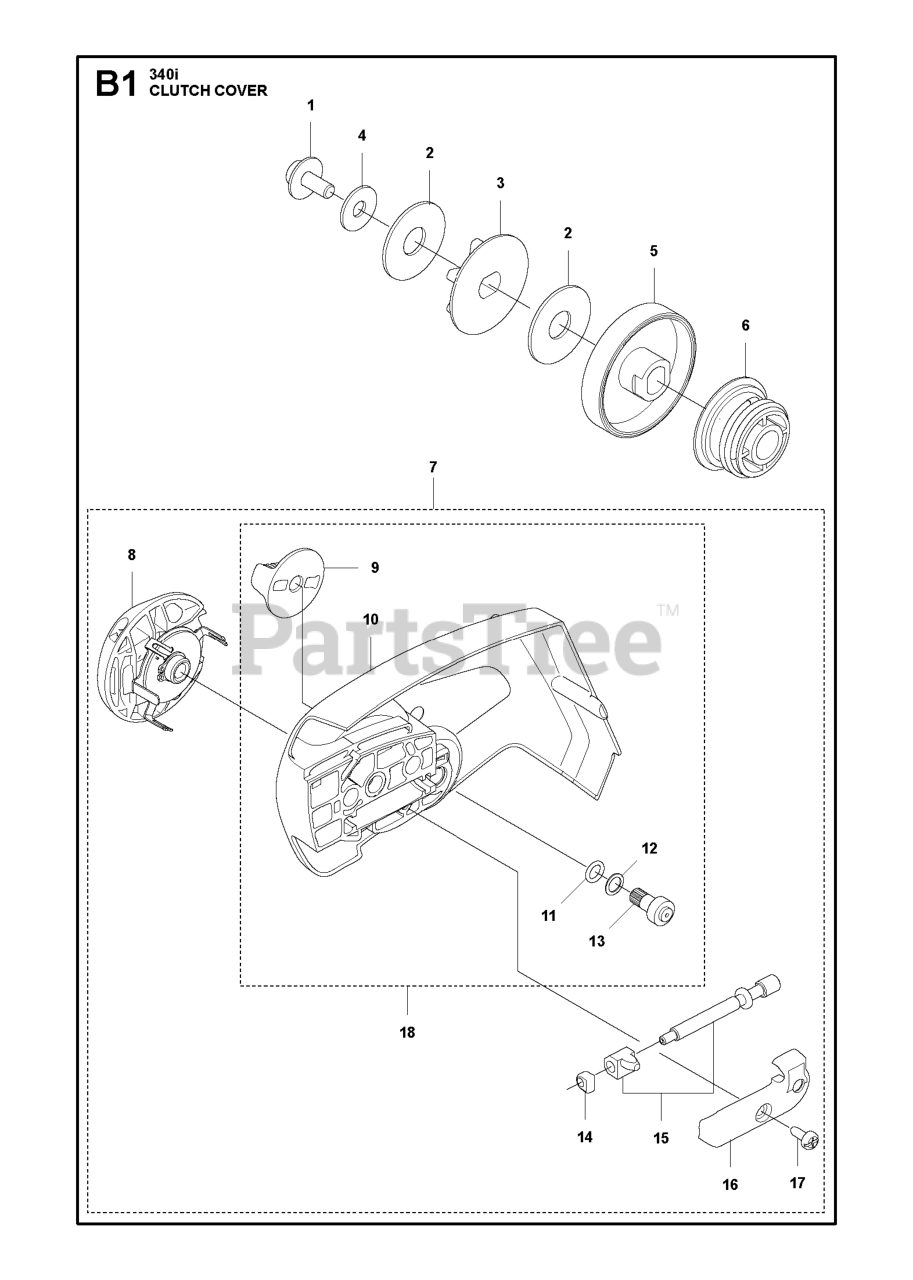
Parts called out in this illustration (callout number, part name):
1	SCREW
3	SPUR SPROCKET 3/8" - 6T
4	WASHER 5.3X15
